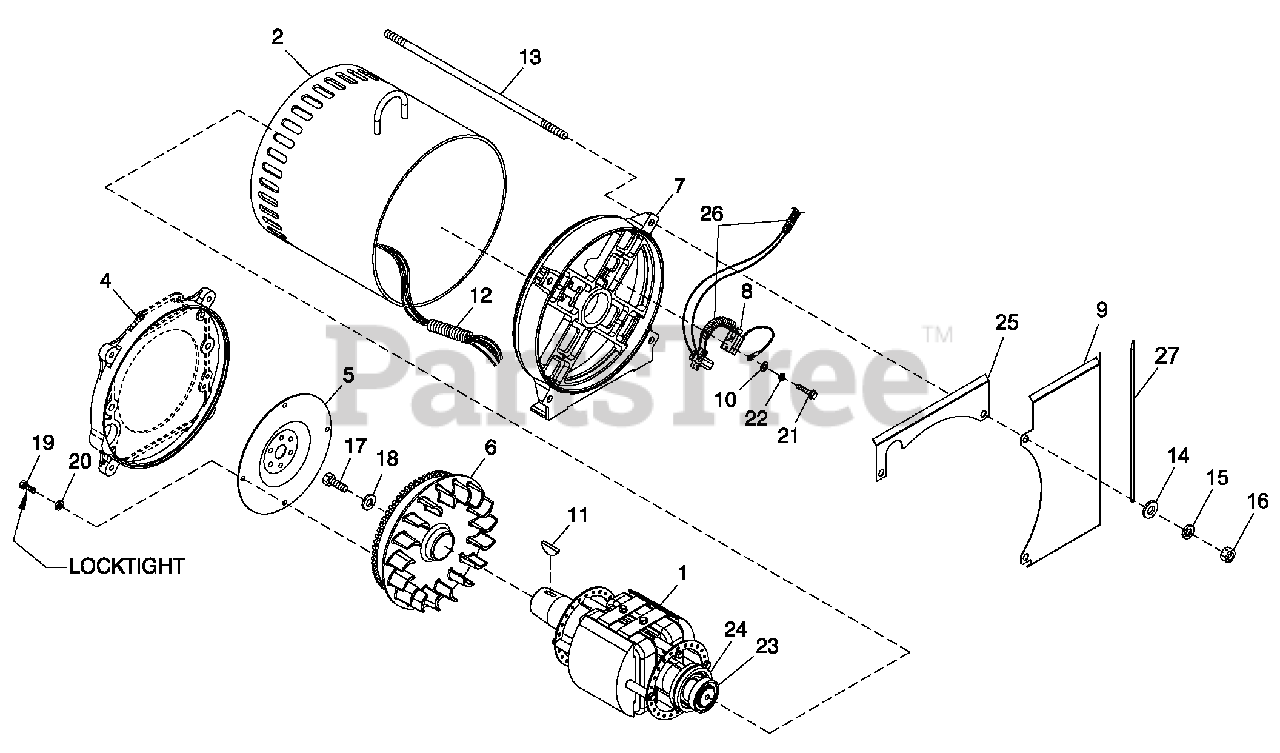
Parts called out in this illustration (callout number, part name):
1	R0T0R-2390-45KD1 CPL
2	STAT0R-390 45K 2P 1PH DIRECT
3	INSTR HYP0T TEST (N0T SH0WN)
4	ENGINE ADAPTER
5	FLEXPLATE
6	ASSY FLYWHEEL CPL W/40MM FAN B
7	REAR BEARING CARRIER 390/DRCT
8	ASSY BRUSH H0LDER 390/HSB
9	GUARD REAR BEARING CARRIER
10	WASHER FLAT #8 ZINC
11	KEY W 00DRUFF #E
12	C0NDUIT FLEX 1.0" ID (35" LG)
13	STUD M 14-2.0 570 G5 ZINC
14	WASHER FLAT M14
15	WASHER L0CKM14
16	NUT HEXM14-2.0G8YEL CHR
17	SCREW HHC M16-2.0X 45 G8.8
18	SPACER .69 X 2.75 X .37 ST/ZNC
19	SCREW HHC M10-1.50 X 16 G10.9
20	WASHER L0CKM10
21	SCREW HHTT M4-0.7X 16 BP
22	WASHER L0CK#8-M4
23	BALL BEARING-45 MM
24	SLIP RING MACHINED
25	GUARD REAR BEARING CARRIER
26	C0NDUIT FLEX .38" ID (60")
27	TRIM VINYL BLACK 1/8GP (16.5"LG)
